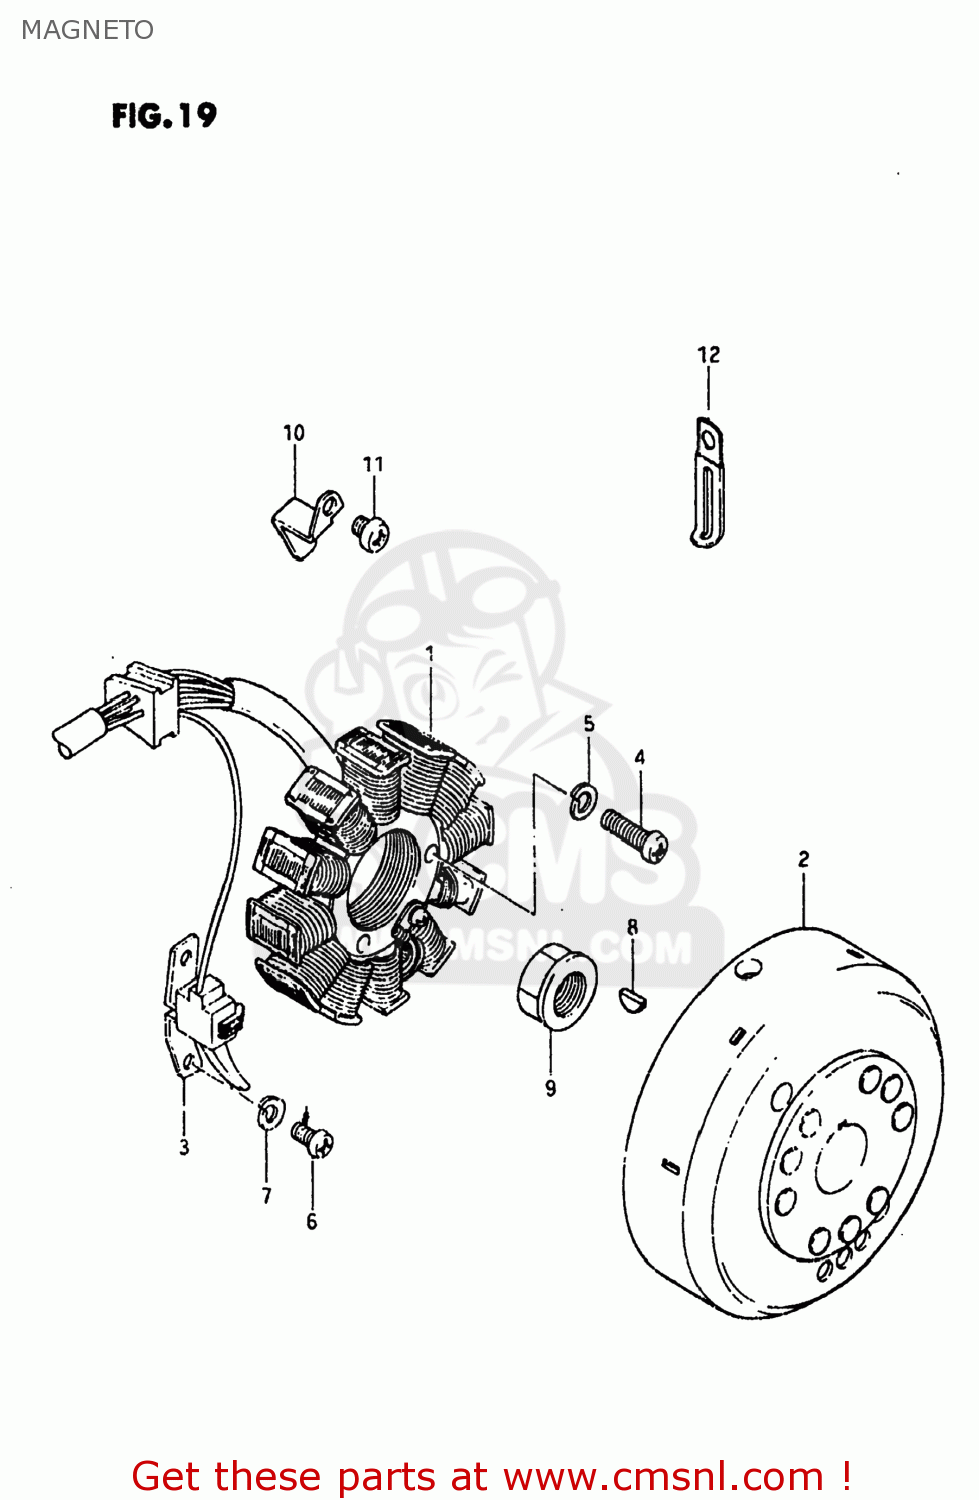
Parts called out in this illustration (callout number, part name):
1	STARTER ASSY
2	ROTOR,FLYWHEEL
3	COIL,PICK UP
4	SCREW
5	LOCK WASHER
6	SCREW
7	LOCK WASHER
8	KEY 4MM
9	NUT,GENERATOR ROTOR
10	CLAMP,MAGNETO LEAD WIRE
11	SCREW
12	CLAMP L:35
